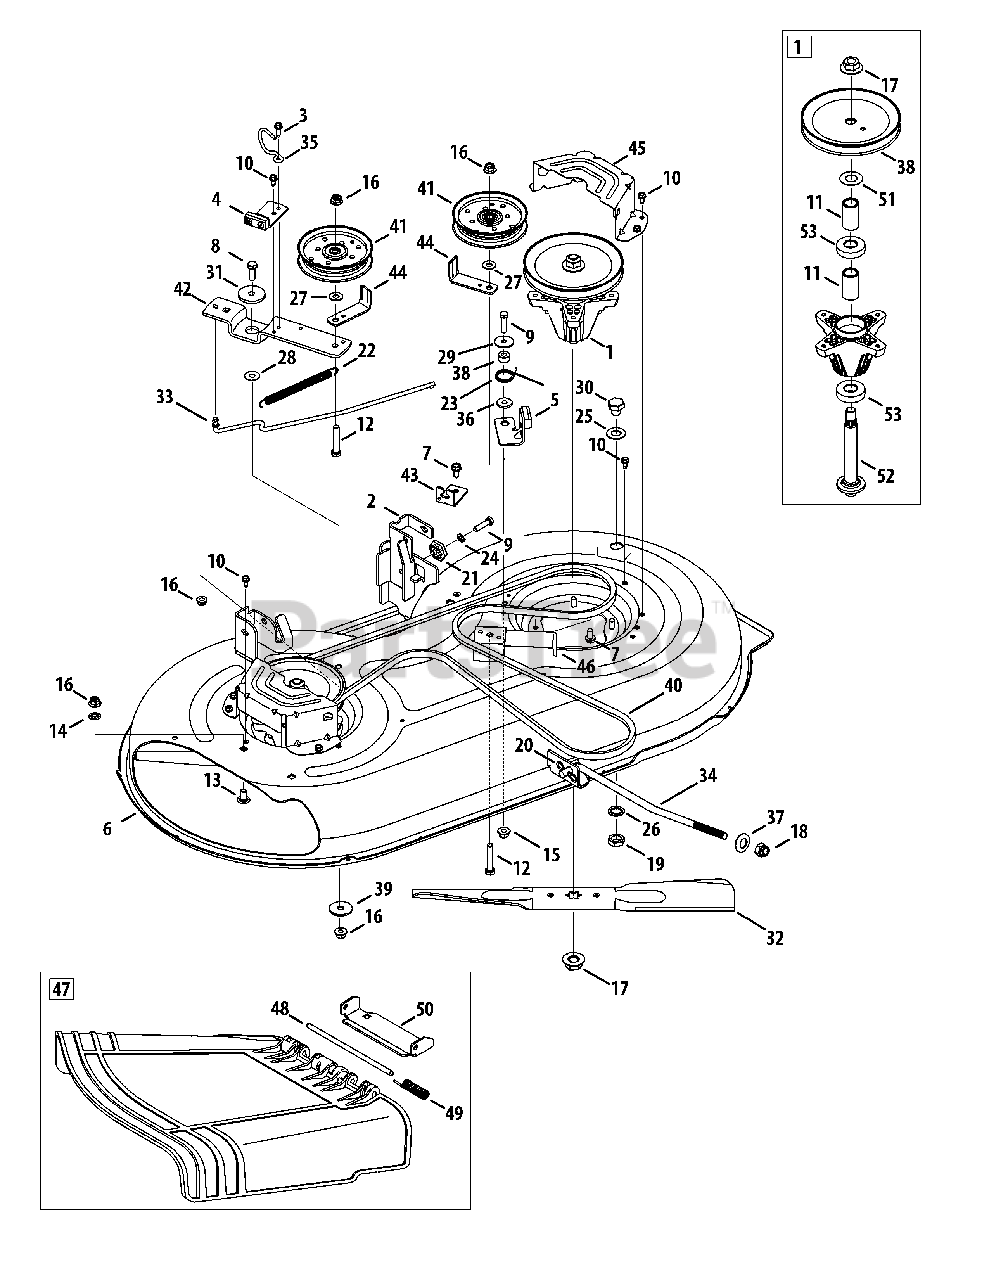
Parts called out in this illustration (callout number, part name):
1	Spindle Pulley Assembly
2	Deck Hanger Bracket Assembly
3	Screw, 1/4-20 x .750
4	Brake Assembly
5	Brake Assembly
6	Deck
7	Screw, 5/16-18 x .750
8	Screw, 3/8-16 x 1.25
9	Hex Screw, 5/16-18 x 1.25
10	Screw, 1/4-20 x .500
11	Spacer, .792 x 1.060 x 1.860
12	Hex Head Screw, 3/8-16
13	Carriage Bolt, 3/8-16 x .75
14	Push Nut, 3/8
15	Flangelock Nut, 5/16-18
16	Flangelock Nut, 3/8-16
17	Flange Nut, 5/8-18
18	Flangelock Nut, 1/2-13
19	Hex Nut, M16 - 1.5
20	Cotter Pin, Bow-Tie
21	Deck Adjuster Gear
22	Extension Spring, .62 x 6.12
23	Torsion Spring, 1.0 x 1.17
24	Lock Washer, 5/16
25	Flat Washer, .64 x 1.24 x .06
26	Flat Washer, .5/8 Int. Tth.
27	Flat Washer, .385 x .870 x .092
28	Flat Washer, .385 x 1.0 x .030
29	Flat Washer, .330 x 1.25 x .06
30	Bolt Plug, M16 x 1.5
31	Shoulder Spacer, .8840 x .190
32	Cutting Blade, 21.23": 2 in 1
33	Brake Control Rod
34	Deck Lift Rod
35	Belt Keeper Rod
36	Shoulder Spacer
37	Deck Lift Pivot Cup
38	Deck Pulley, 6.3 dia.
39	Flat Washer, .406 x 1.50 x .105
40	V-Type Belt, 96.5
41	Idler Pulley, 4.25 Diameter
42	Idler Pivot Bracket
43	Deck Cable Engagement Bracket
44	Belt Pulley Guard
45	Deck Belt Cover
46	Deck Support Bracket
47	Chute Deflector Assembly
48	Hinge Pin
49	Torsion Spring, .44 x 2.0
50	Chute Bracket
51	Flat Washer, .760 x 1.50
52	Spindle Shaft
53	Ball Bearing, .787 x 1.85 x .551
